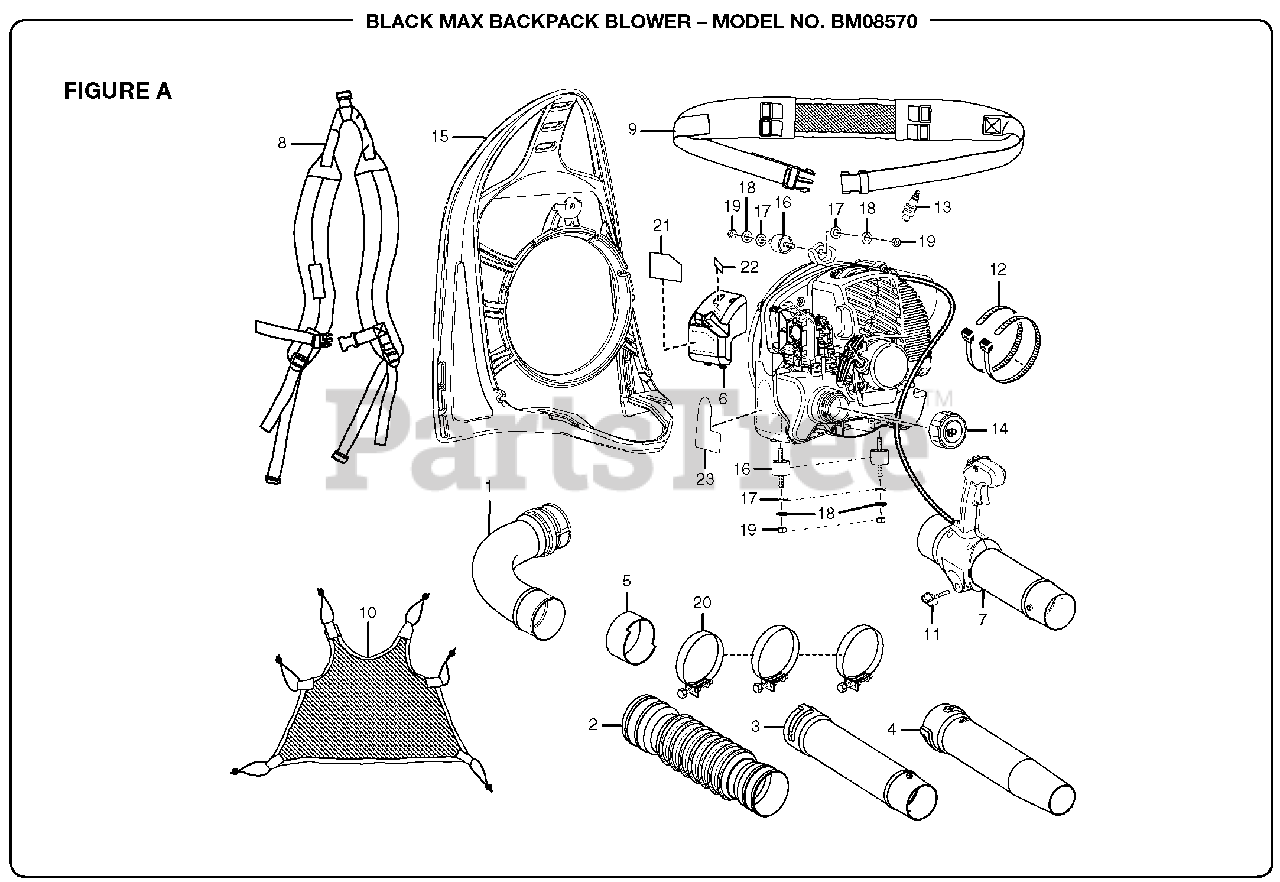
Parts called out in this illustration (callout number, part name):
1	Elbow Tube
3	Straight Tube (Upper Tube)
4	Nozzle (Lower Tube)
6	Air Filter Cover
7	Throttle Control Handle
8	Shoulder Harness Assembly
9	Waist Harness
10	Mesh Backing
11	Throttle Control Handle Screw
12	Cable Tie
13	Spark Plug (Champion RCJ6Y)
14	Fuel Cap Assembly
15	Backpack Frame
16	Vibration Isolators
18	Spring Washer
19	Hex Nut (1/4-20)
20	Tube Clamp
21	Starting Label
22	Choke Label
23	Warning Label
